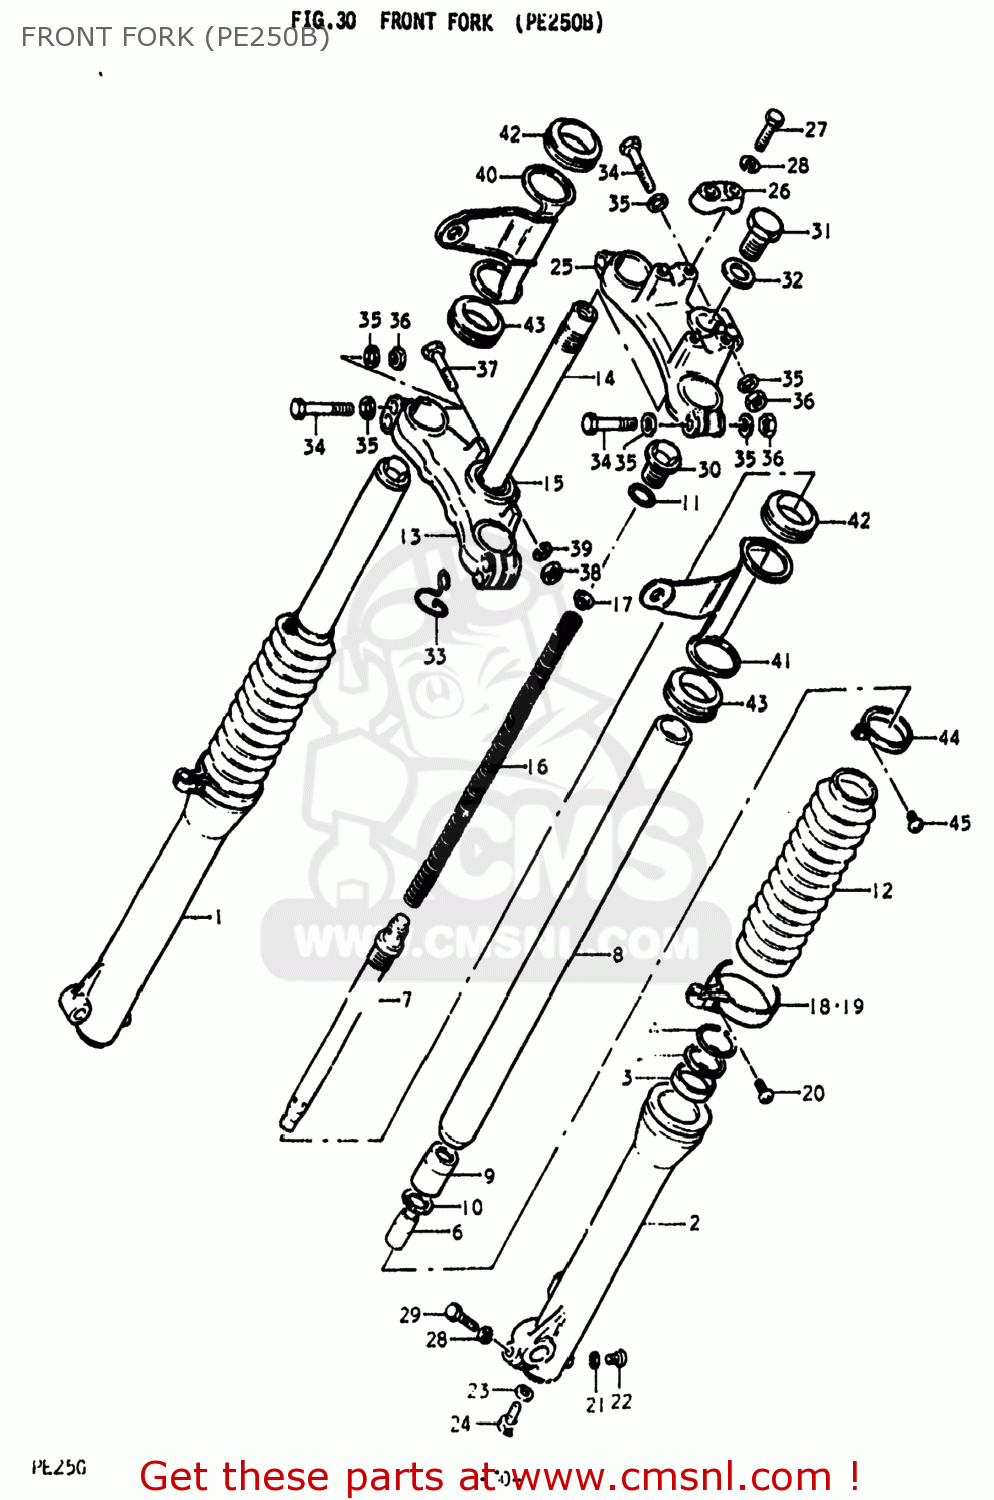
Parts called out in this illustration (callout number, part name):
1	TUBE,OUTER,RIGHT
2	TUBE,OUTER,LEFT
3	OIL SEAL,FRONT FORK
4	CIRCLIP,FORK OIL SEAL
5	RING,FORK BACK UP
6	PIECE,OIL LOCK
7	CYLINDER,FRONT FORK
8	TUBE,FORK,INNER
9	PISTON,FORK INNER TUBE
10	RING
11	O RING
12	BOOT
13	STEM,STEERING
14	STEM,STEERING
15	RACE,STEERING OUTER LWR
16	SPRING
17	GUIDE,FRONT FORK SPRING C
18	BAND,FRONT FORK COVER
19	BAND,FRONT FORK COVER
20	SCREW 4X10
21	GASKET,DRAIN,PLUG (NAS)
22	SCREW
23	GASKET (NAS)
24	BOLT,FORK CYLINDER(10X25)
25	HEAD,STEERING STEM
26	HOLDER,HANDLEBAR
27	BOLT
28	LOCK WASHER
29	BOLT (8X30)
30	BOLT,FORK
31	BOLT,STEERING STEM HEAD
32	WASHER
33	CLAMP,METER CABLE
34	BOLT
35	WASHER
36	NUT
37	BOLT 10X60
38	NUT
39	LOCK WASHER
40	BRACKET,HEADLAMP,RIGHT
41	BRACKET,HEADLAMP,LEFT
42	GASKET
43	CUSHION,HEADLAMP BRACKET
44	BAND,BOOT
45	SCREW
